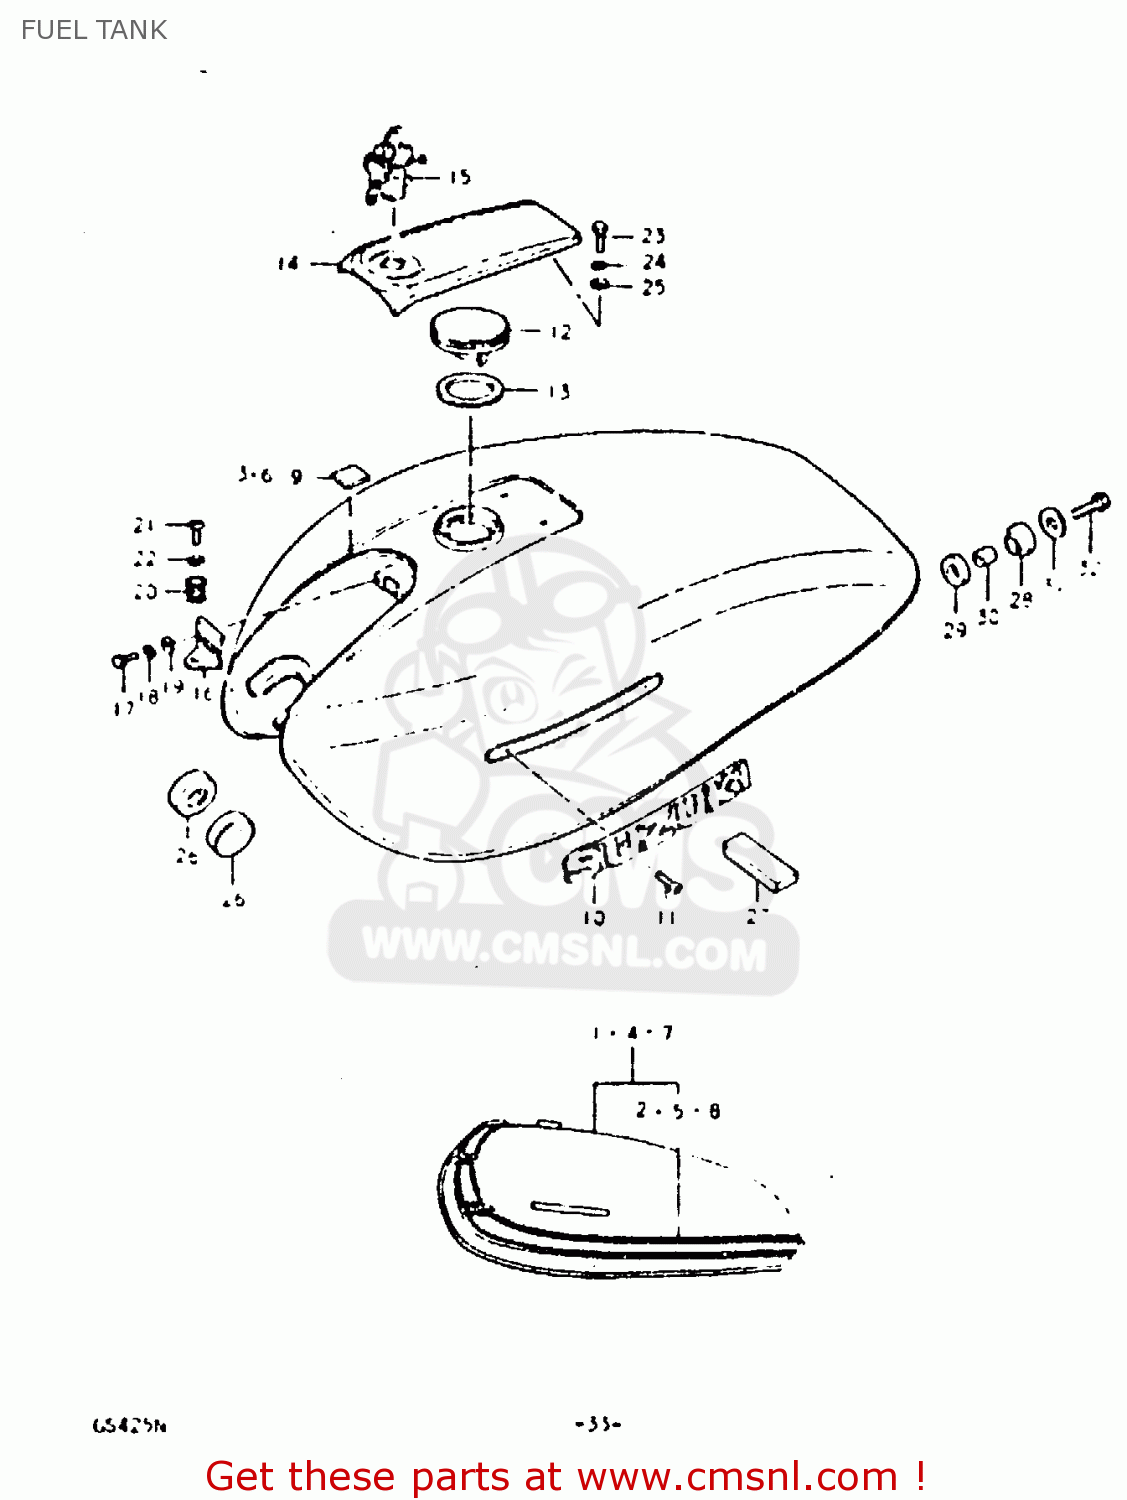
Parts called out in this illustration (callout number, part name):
1	TANK, FUEL
2	TAPE SET
3	CUSHION,FUEL TANK FR COVER
4	TANK, FUEL
5	TAPE SET
6	CUSHION,FUEL TANK FR COVER
7	TANK, FUEL
8	TAPE SET
9	CUSHION,FUEL TANK FR COVER
10	EMBLEM,FUEL TANK
11	SCREW 3X6
12	CAP,FUEL TANK
13	GASKET (NAS)
14	COVER,FUEL TANK
15	LOCK,FUEL TANK FR COVER
16	HOLDER,FUEL TANK FRONT COVER
17	BOLT
18	LOCK WASHER
19	WASHER
20	SPRING
21	SCREW
22	LOCK WASHER
23	BOLT
24	LOCK WASHER
25	WASHER 5MM
26	CUSHION
27	CUSHION
28	CUSHION
29	CUSHION
30	SPACER(8.5X12X19)
31	WASHER
32	BOLT (8X30)
